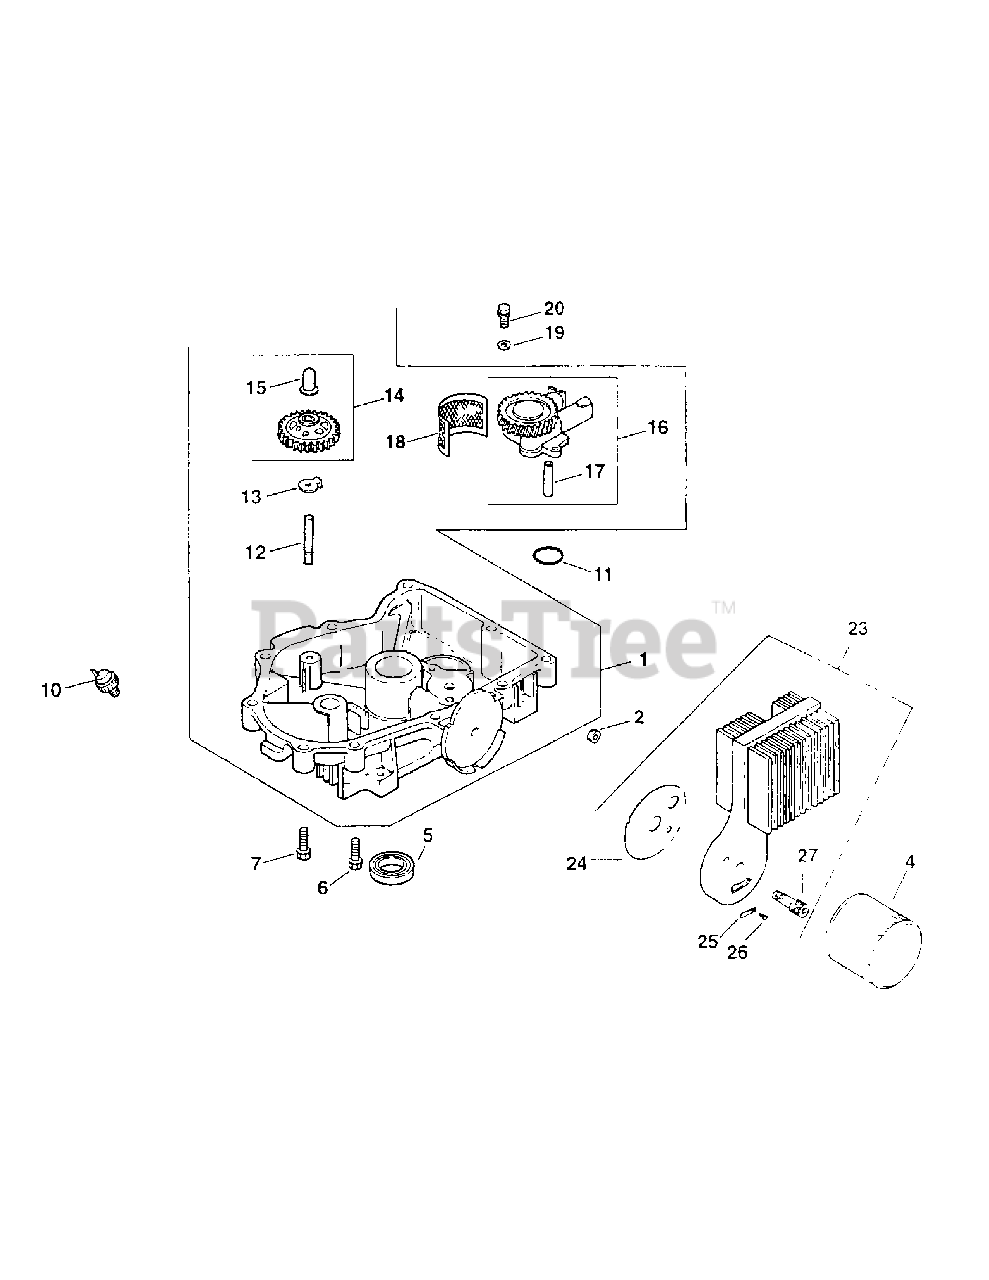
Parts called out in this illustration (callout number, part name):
1	Oil Pan Assembly
2	Plug, Allen Head 3/8"
4	Filter, Oil
5	Seal, Oil (P.T.O. End)
6	Screw, Hex Flange
7	Screw, Hex Flange
10	Switch, Oil Pressure
12	Shaft, Governor Gear
13	Tab, Locking
14	Kit, Governor Gear w/Pin
15	Pin, Governor Regulating
16	Oil Pump Assembly
17	Tube, Oil Pickup
18	Screen, Oil Pickup
19	Washer, Plain 6mm
20	Screw, Hex Flange
23	Kit, Oil Cooler
24	Gasket, Oil Filter Adapter
25	Reed, Oil relief
26	Screw, Hex Cap
27	Nipple, Oil Filter
